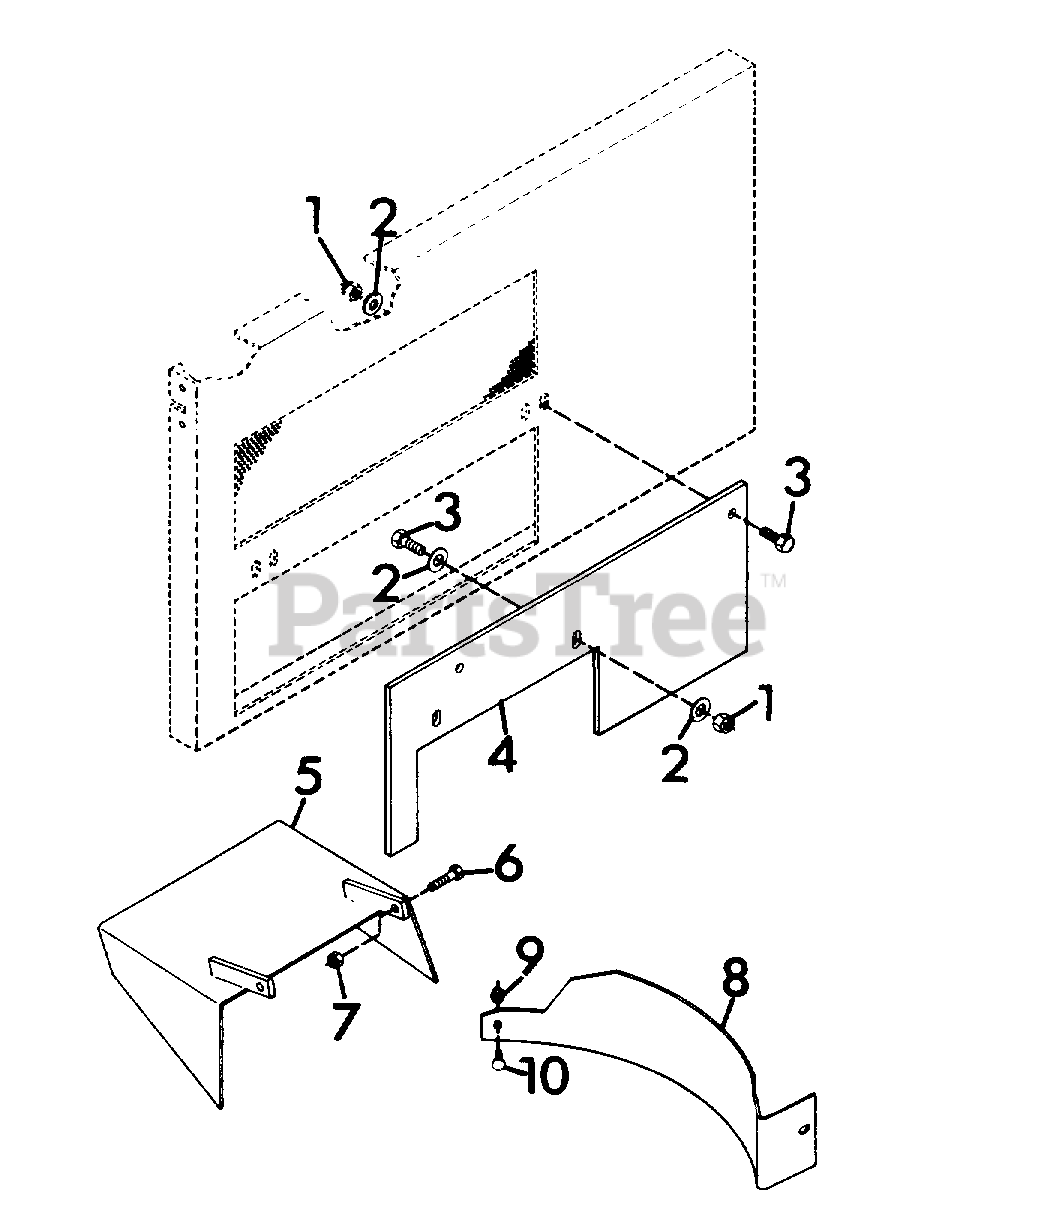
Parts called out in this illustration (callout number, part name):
1	NUT, LOCK 3/8-16
2	WASHER, FLAT .406X.812X.065
3	BOLT, HEX 3/8-16X1.00
4	ADAPTER, PRO 40
5	WELDMENT, DISCHARGE CHUTE
6	BOLT, HEX 5/16-18X1.25
7	NUT, LOCK 5/16-18
8	BAFFLE
9	NUT, LOCK 1/4-20
10	BOLT, 1/4-20X.75 RD HD SQ NK
